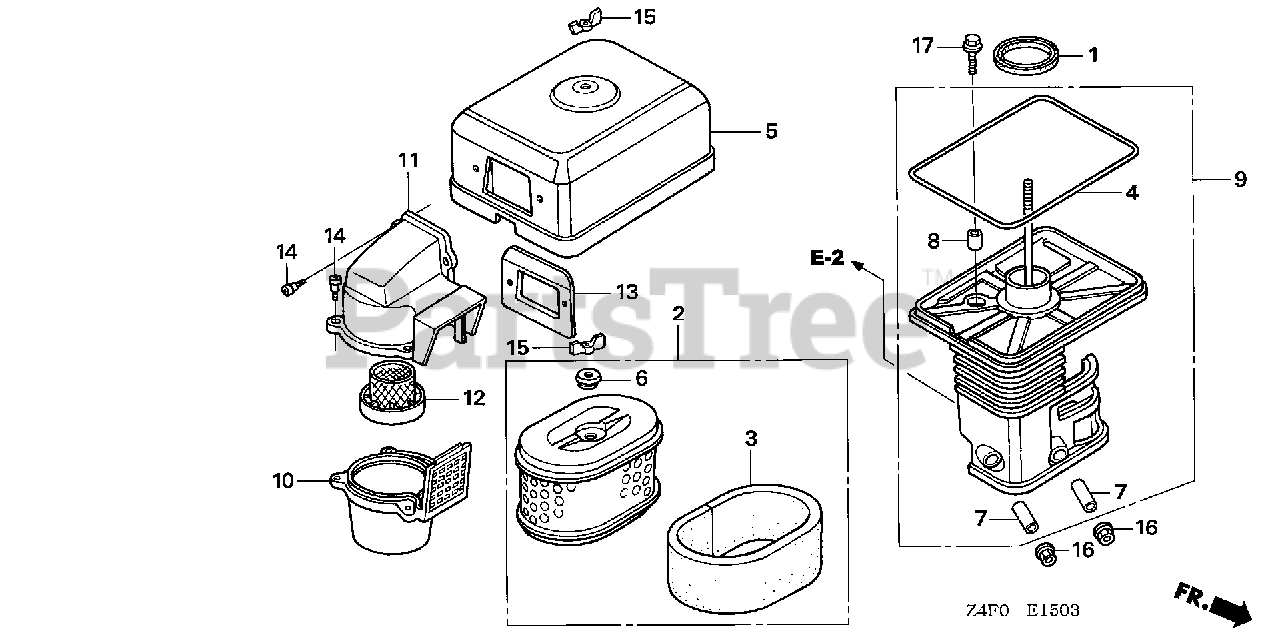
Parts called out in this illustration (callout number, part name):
1	GASKET, ELBOW
2	ELEMENT, AIR CLEANER (DUAL)
3	FILTER (OUTER)
4	GASKET, AIR CLEANER COVER
5	COVER, AIR CLEANER (CYCLONE)
6	GROMMET, AIR CLEANER
7	COLLAR, AIR CLEANER
8	COLLAR B, AIR CLEANER
9	ELBOW, AIR CLEANER
10	CASE, PRE AIR CLEANER
11	CAP, PRE AIR CLEANER
12	GUIDE, PRE AIR CLEANER
13	PLATE, PRE AIR CLEANER
14	BOLT, SPLASH GUARD
15	NUT, TOOL BOX SETTING
16	NUT, FLANGE (6MM)
17	BOLT, FLANGE (6X20)
